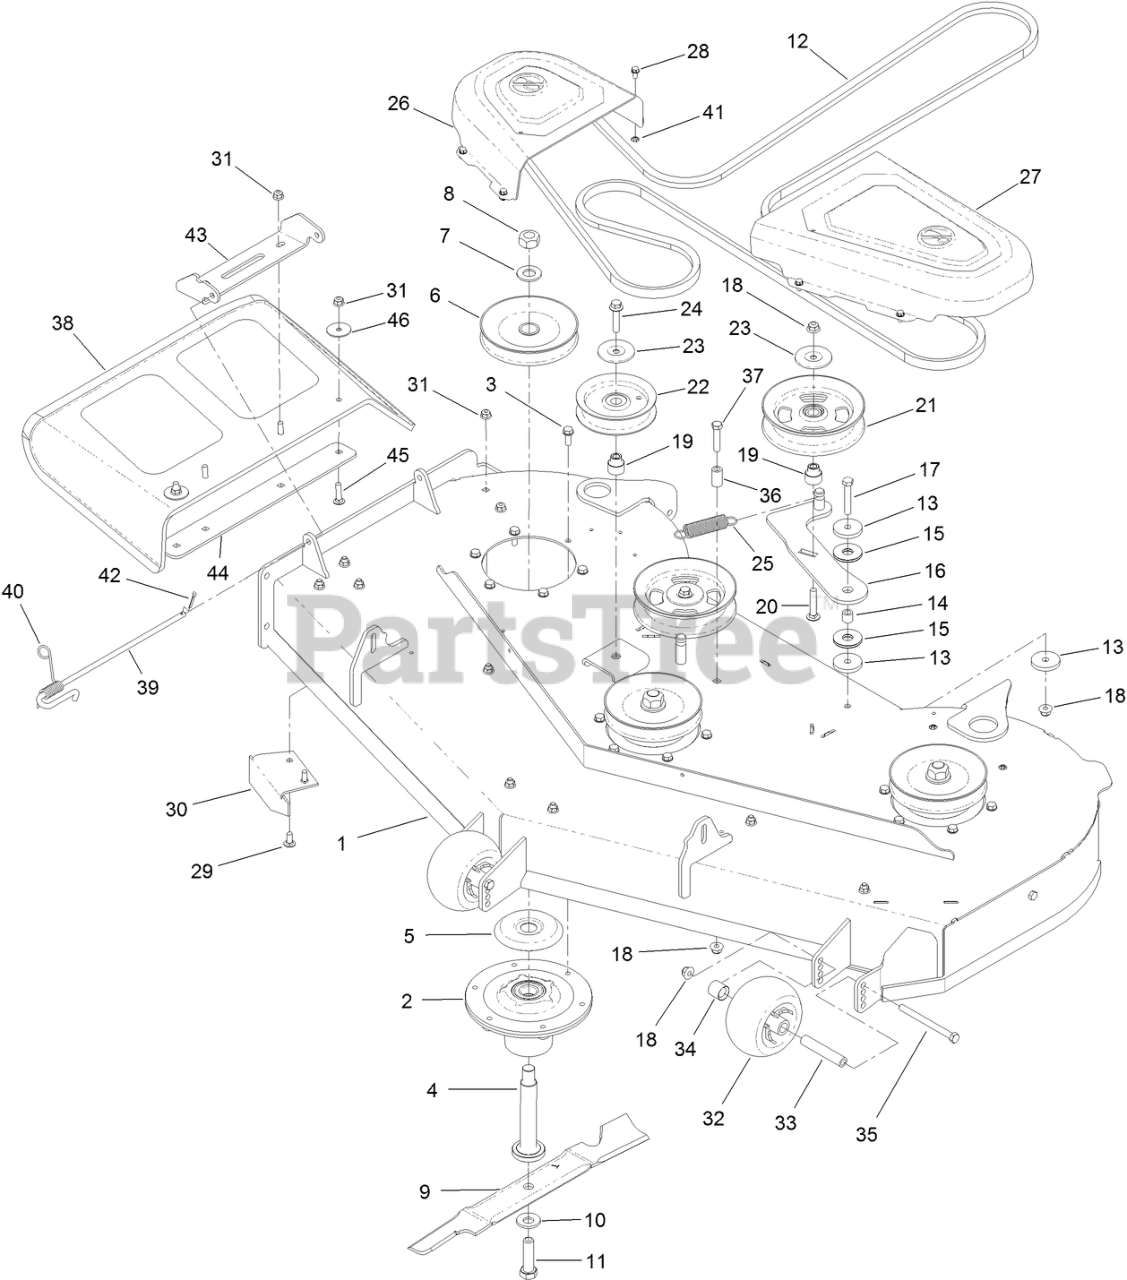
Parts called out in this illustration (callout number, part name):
1	DECK ASM-54"
2	SPINDLE ASM
3	SCREW-TAPTITE
4	SHAFT-SPINDLE
5	SHIELD-BEARING
6	PULLEY
7	WASHER
8	NUT-HEX
9	BLADE - HI FLOW, 18.75 IN
10	WASHER-BELLEVILLE
11	SCREW-BLADE
12	BELT-V
13	WASHER-PLAIN
14	BUSHING-IDLER
15	WASHER-FRICTION, COMPOSITE
16	IDLER ARM ASM
17	SCREW-HH
18	NUT-HF, NI
19	BUSHING-IDLER
20	SCREW-CARR
21	PULLEY-IDLER, FLAT
22	PULLEY-IDLER, FLAT
23	SHIELD-DUST
24	SCREW-HHF
25	SPRING-EXTENSION
26	COVER-BELT, RH
27	COVER-BELT, LH
28	SCREW-HWH
29	SCREW-CARR
30	BAFFLE-CUTOFF
31	NUT-HF, NI
32	ROLLER-SCALP, ANTI
33	TUBE-SPANNER
34	SPACER-AXLE, REAR
35	SCREW-HH
36	SPACER-FENDER
37	SCREW-HH
38	DEFLECTOR
39	PIN-CHUTE
40	SPRING-TORSION
41	NUT-RETAINING
42	PIN-COTTER
43	BRACKET UPPER, DEFLECTOR
44	PLATE-DEFLECTOR
45	SCREW-CARR
46	WASHER-FLAT
